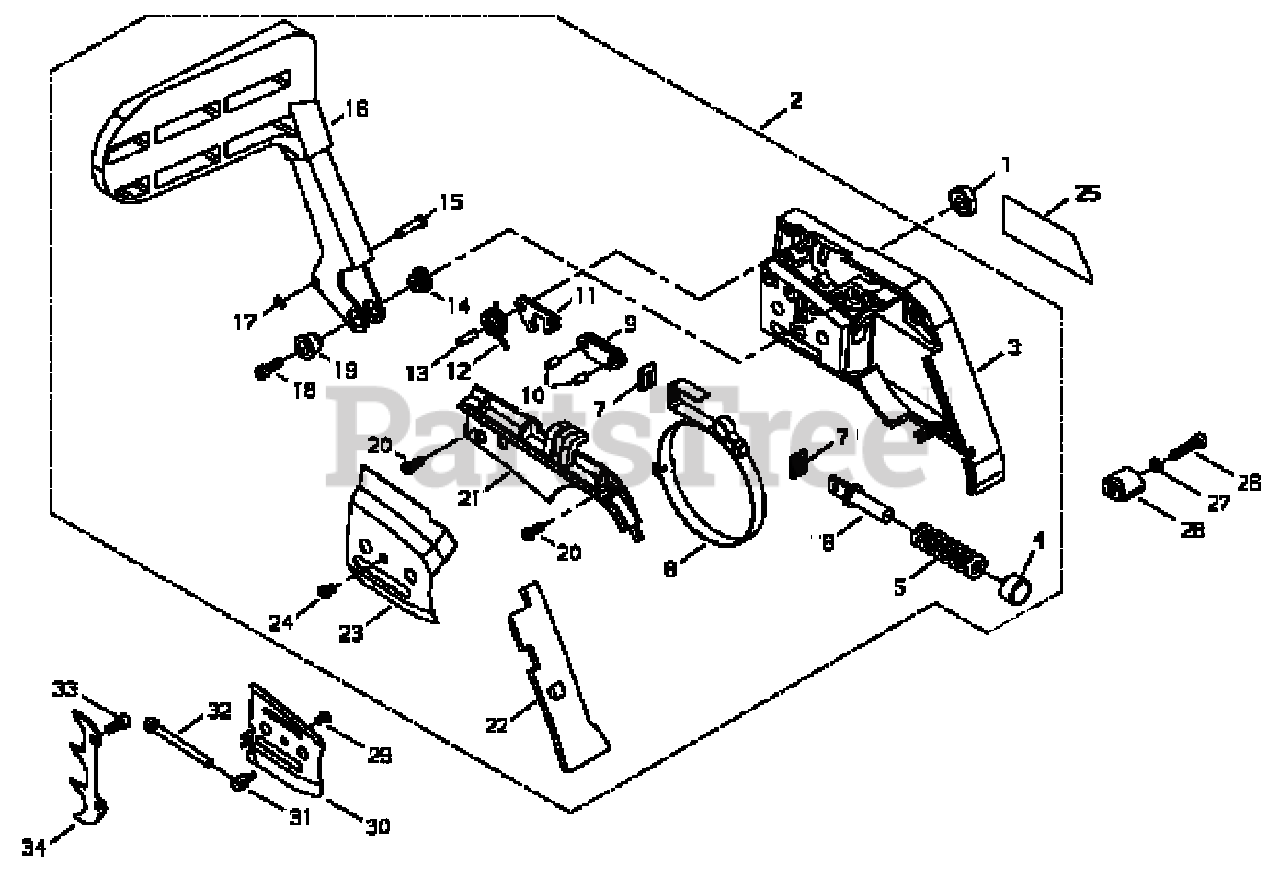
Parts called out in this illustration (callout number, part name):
1	NUT - 8
2	CHAIN BRAKE ASSY
3	GUARD, SPROCKET
4	STOPPER
5	SPRING, BRAKE
6	HOLDER, SPRING
7	ADJUST PLATE
8	BAND, BRAKE
9	TIE, CABLE
10	PIN - LOCATING
11	LEVER - INNER
12	SPRING, LEVER
13	PIN
14	NUT
15	PIN
16	LEVER, BRAKE
17	RING, RETAINING
18	SCREW - 4X12
19	COLLAR
20	SCREW - 4X12 -- TAPPING
21	COVER, BRAKE
22	PROTECTOR
23	GUIDE PLATE D
24	SCREW - 4X8 -- TAPPING
25	LABEL - TRADE
26	BOLT
27	WASHER
28	CATCHER, CHAIN
29	SCREW
30	GUIDE PLATE C
31	TENSIONER, CHAIN
32	SCREW, TENSIONER
33	BOLT
34	SPIKE
